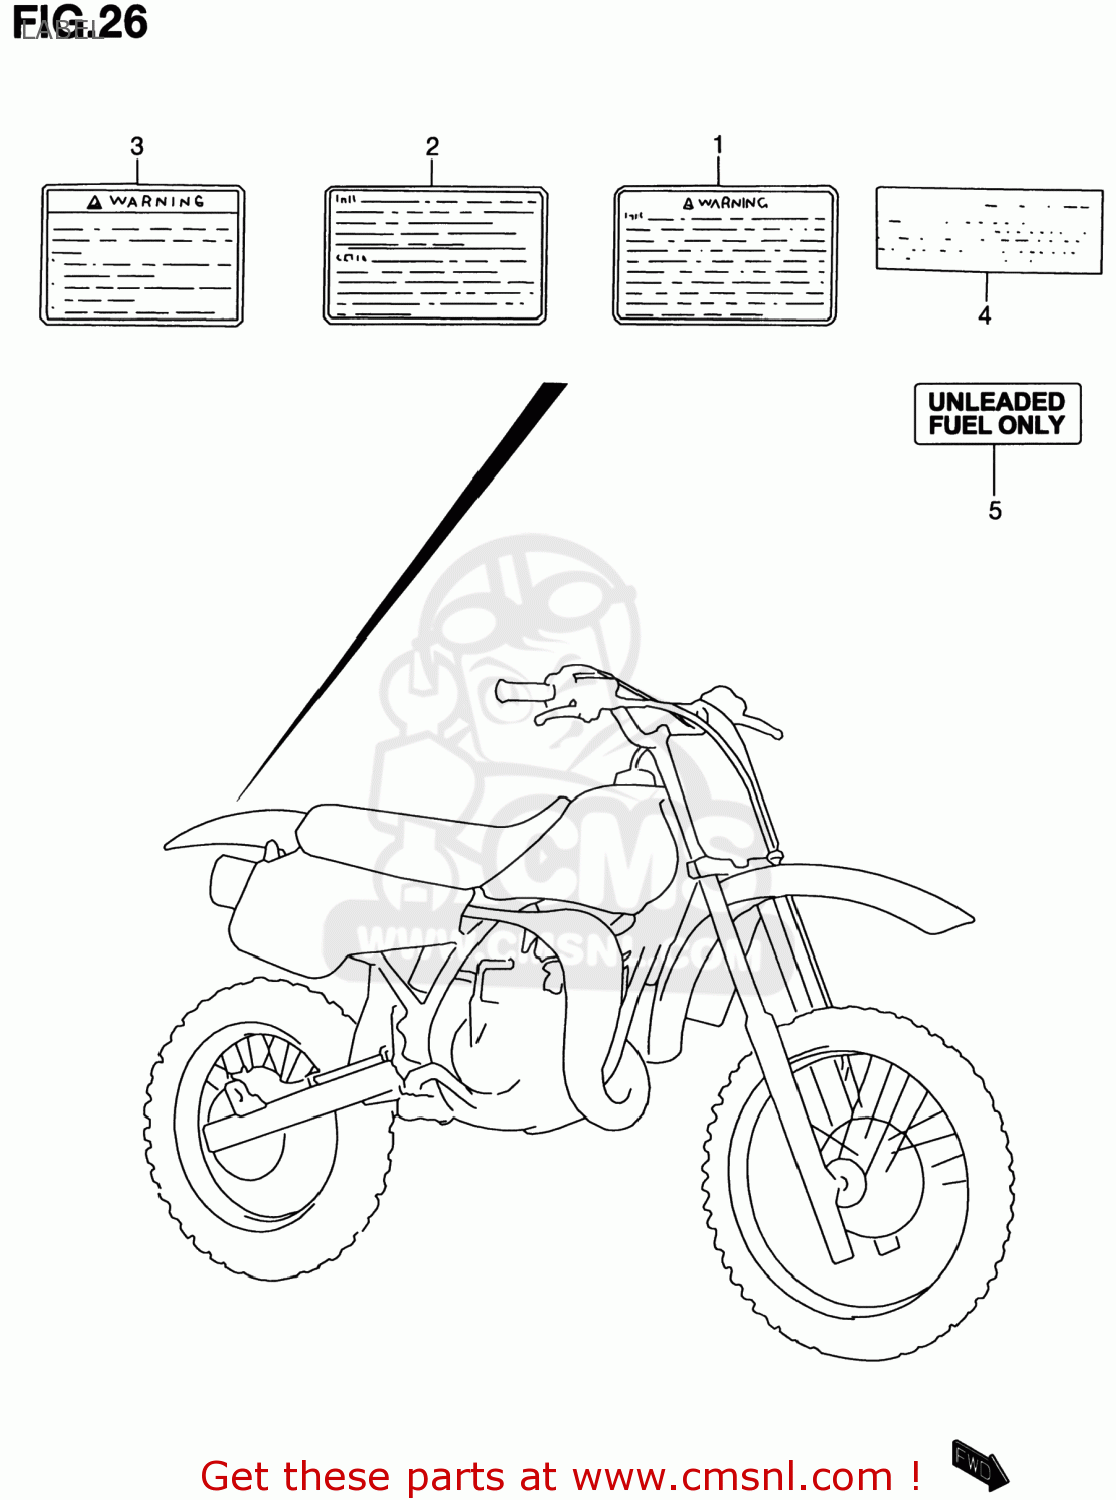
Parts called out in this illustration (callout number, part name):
1	LABEL,WARNING
2	LABEL,WARNING
3	LABEL,GENERAL WARNING
4	LABEL (MANUAL NOTICE)
5	LABEL,UNLEADED FUEL
6	MANUAL,OWNER'S RM80Y
